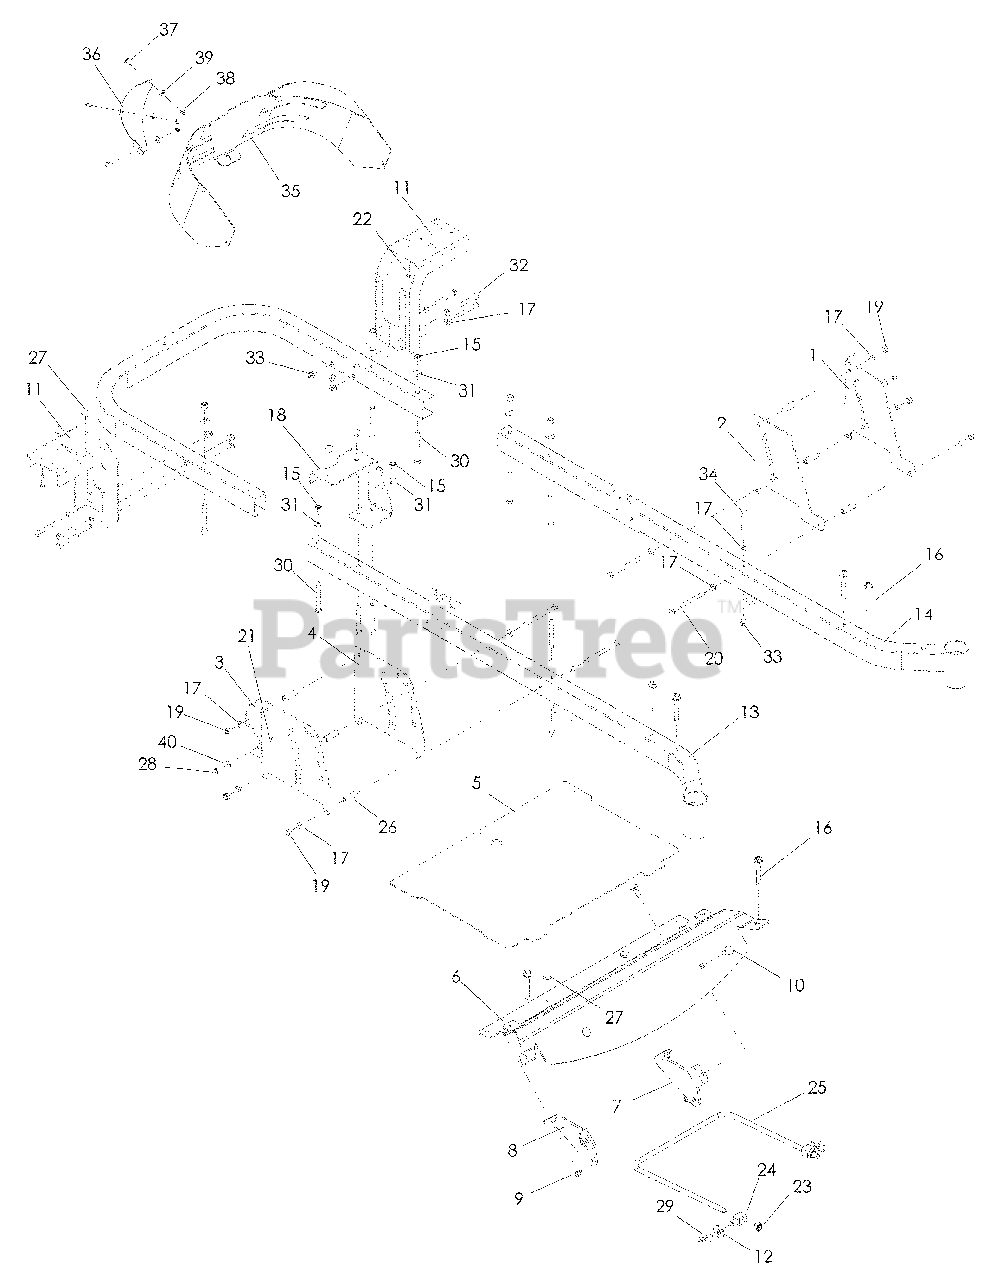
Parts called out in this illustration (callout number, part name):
1	PLATE, OUTER BRAKE
2	PLATE, BRAKE LATCH
3	PLATE, OUTER HEIGHT
4	PLATE, INNER HEIGHT
5	FOOT PLATE w/DECALS
7	MOUNT, STRUT, RT
8	MOUNT, STRUT, LT
9	NUT 3/8-16 HEX FLG NYLOC
10	RHSNB 3/8-16 x 1
11	SUPPORT, FENDER
12	WASHER ½ FLAT
13	FRAME, FRONT RT
14	FRAME, FRONT LT
15	NUT 3/8-16 HEX NYLOC
16	BOLT 3/8-16 x 25/8 THD FRM
17	WASHER 5/16 SAE FLAT
18	SUPPORT, TANK
19	NUT 5/16-18 HEX NYLOC
20	HCS 5/16-18 x 4
21	HCS ¼-20 x 1
22	SCREW 10-12 x 1½ WSH HD
23	NUT 7/16-14 HEX NYLOC
25	LINK, FRONT SUSPENSION
26	SPACER ½ OD x 1½
27	GROMMET, BUMPER
28	NUT ¼-20 HEX NYLOC
30	HCS 3/8-16 x 3
31	WASHER 3/8 SAE FLAT
32	HCS 5/16-18 x 2¼
33	NUT 5/16-18 FLANGE NYLOC
34	HCS 5/16-18 x 2¾
35	GUARD, WIDE ENGINE
36	SUPPORT, CORNER
37	RHSSNB ¼-20 x 5/8
38	NUT ¼-20 HEX NYLOC
39	WASHER ¼ FLAT
40	WASHER ¼ FLAT SAE
